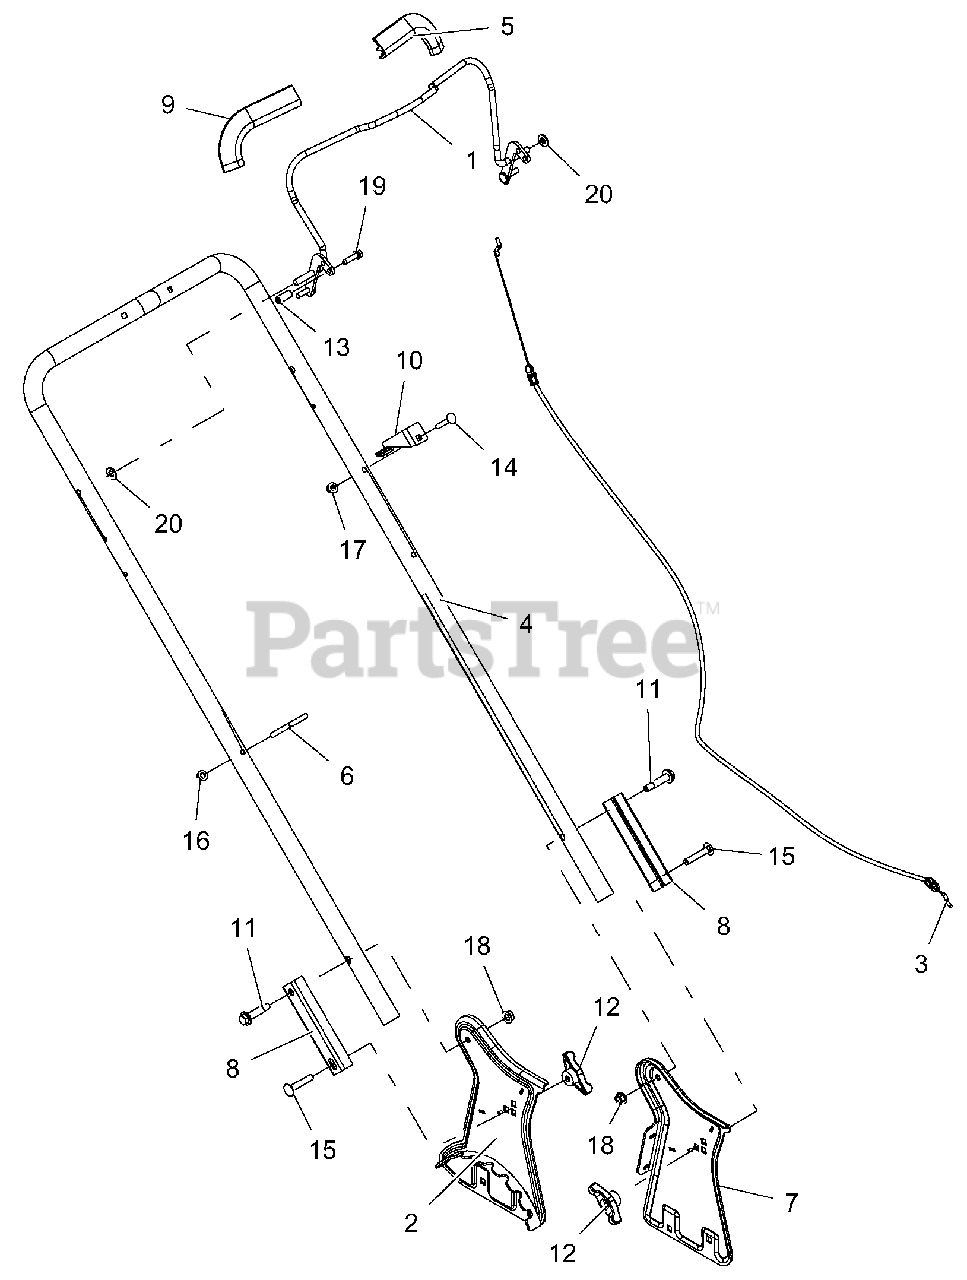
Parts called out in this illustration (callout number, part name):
1	WLDMT, OPC BAIL
2	SUPPORT, RH HANDLBAR
3	CABLE, OPC
4	HANDLEBAR, LM
5	GUARD, FINGER - LH
6	HOLDER, RECOIL CORD
7	SUPPORT, LH HANDLEBAR
8	BRKT, HANDLEBAR FIXED ADJUST
9	GUARD, FINGER - RH
10	BRKT, CABLE ANCHOR - LM PUSH
11	BLT-SHLDR, .50X1.15X.312-18GR5
12	KNOB,WING .31-18 UNC NYL/TALC
13	CAP, VINYL, .25 ID
14	@BLT-RDHDSQNK .25-20X1.50 G5YZ
15	@BLT-RDHDSQNK .31-18X1.75 G5YZ
16	@NUT-LK-NYL-FLG .25-20 YWZC
17	@NUT-LK-TOP-FLG .25-20 YWZC
18	@NUT-LK-TOP-FLG .31-18 YWZC
19	@SCR-TAP .25-20X1.00 HWH TR YZ
20	@WSHR-FL-STL.344X.688X.065YWZC
